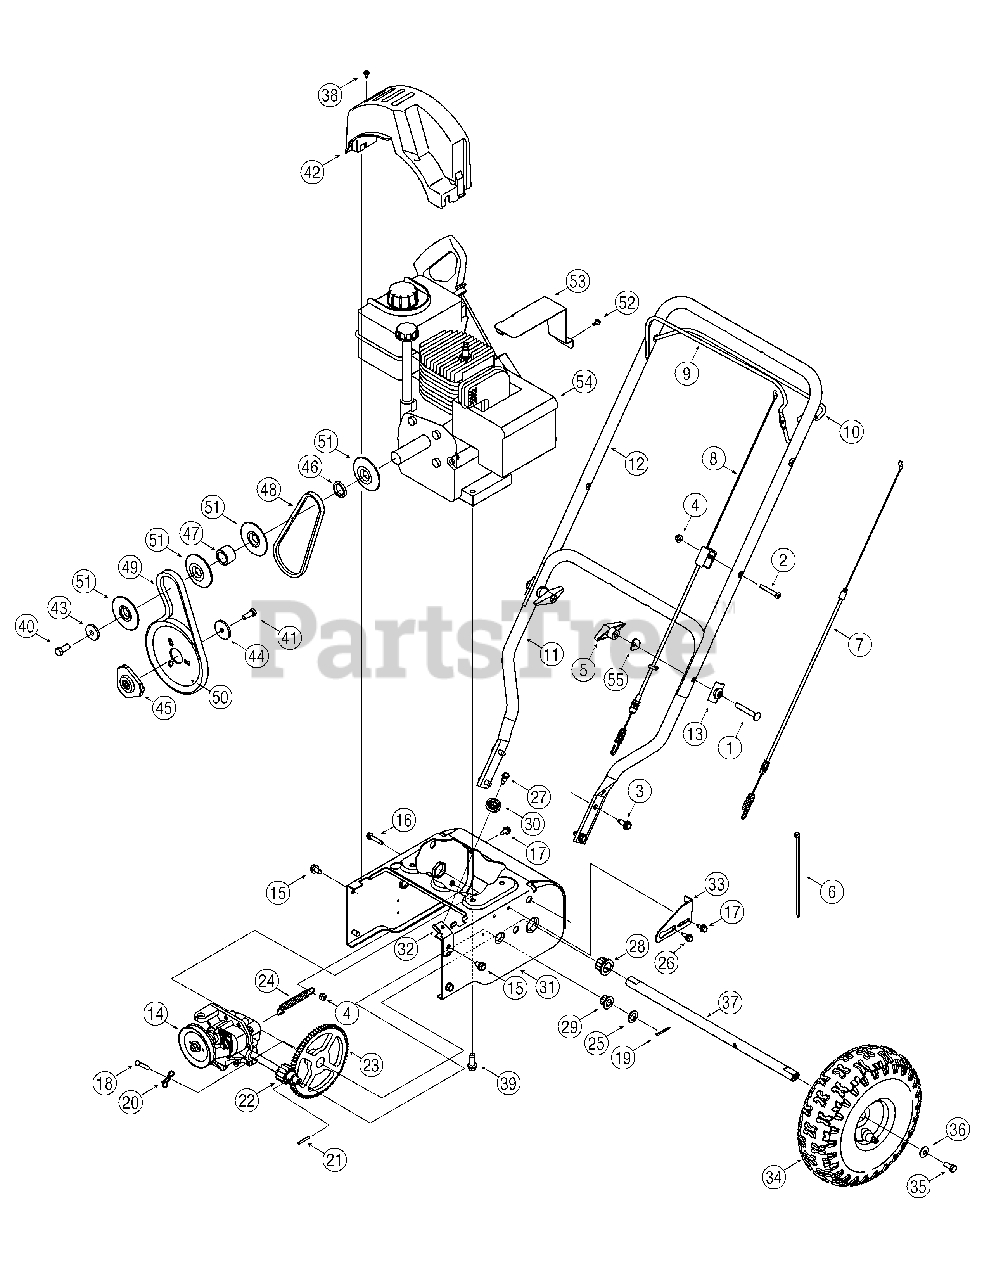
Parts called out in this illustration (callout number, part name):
1	Carriage Screw 5/16-18 x 2.25"
2	Mach. Screw 1/4-20 x 1.825"
3	Screw, 5/16-18 x .75"
4	Flange Lock Nut 1/4-20
5	Nut Knob 5/16-18
6	Cable Tie
7	Drive Cable
8	Auger Cable
8	Fitting, Dual Cable
9	Auger Control
10	Drive Control
13	Handle Tab
14	Transmission Assembly
15	AB Screw 5/16-18 x .625
16	TT Screw 1/4-20 x 1.25"
17	Screw, 1/4-20 x.625"
18	Clevis Pin
19	Cotter Pin, 1/8 x 1.0
20	Bow Tie Cotter Pin 72
21	Roll Pin
22	Pinion 14T
23	Gear 70T
24	Extension Spring
25	Flat Washer
26	Shoulder Screw 1/4-20
27	Carriage Screw 1/4-28
28	Hex Flange Bearing
29	Hex Flange Bearing
30	Cable Roller
32	Auger Cable Bracket
34	Wheel Assembly Snow Hog Gray
35	Lock Bolt 5/16-24 x 0.75"
36	Bell Washer
38	Hex Screw, #10-16 x.500
39	TT Sems Screw 3/8-16 x 1.0"
40	Hex Bolt 3/8-24 x 0.875"
41	Lock Bolt 5/16-24 x .0875
42	Belt Cover
43	Flat Washer,.406ID x 1.25 0D
44	Flat Washer,.34ID x 1.50 OD
45	Pulley: Adapter,.75 Dia.
46	Spacer, .876 x 1.25 x.19
47	Spacer, .876 x 1.25 x .86
48	V-Belt, 3/8 x 21.108 Lg.
49	V-Belt, 3/8 x 26.375 Lg.
50	Auger Pulley
51	Pulley Half
52	Screw, #10-16 x.500
53	Heat Shield
54	5.0HP Tecumseh Engine
55	Saddle Washer
